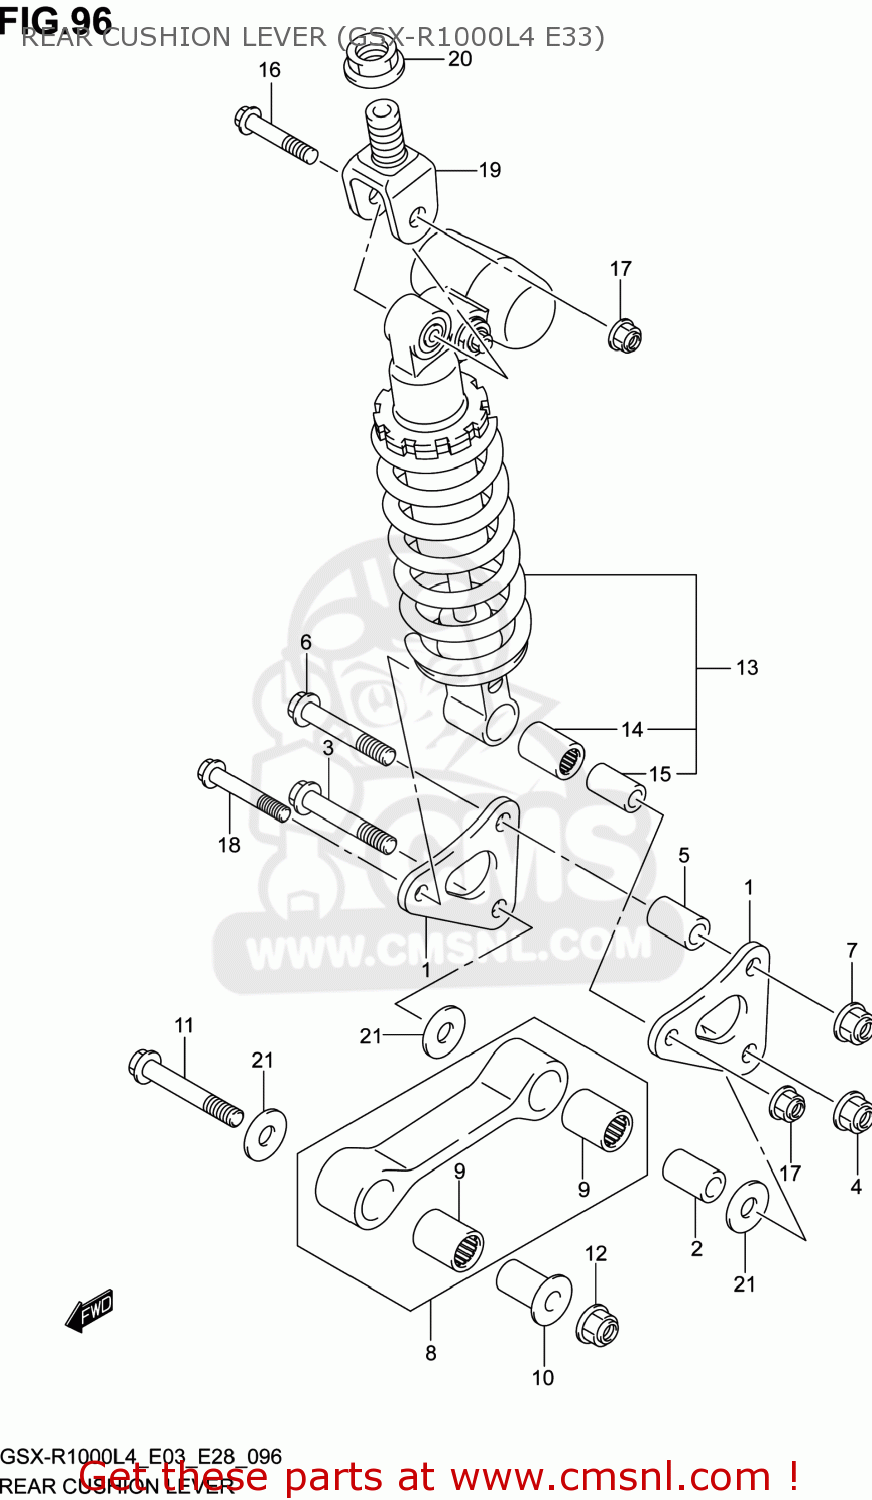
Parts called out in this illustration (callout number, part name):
1	LEVER,RR CUSHION
2	SPACER,RR CUSHION LEVER FR
3	BOLT,RR CUSHION LEVER
4	NUT
5	SPACER,RR CUSHION LEVER FR
6	BOLT,RR CUSHION LEVER
7	NUT
8	ROD SET,RR CUSHION LEVER
9	BEARING(20X27X32)
10	SPACER,RR CUSHION ROD FR
11	BOLT,RR CUSHION ROD
12	NUT
13	ABSORBER ASSY,RR SHOCK
14	BEARING(17X24X32)
15	SPACER,RR SHOCK ABS LWR
16	BOLT(10X55)
17	NUT
18	BOLT,RR SHOCK ABSORBER LWR
19	BRACKET,RR SHOCK ABSORBER UPR
20	NUT,RR SHOCK ABS BRACKET
21	WASHER(12X34X1)
